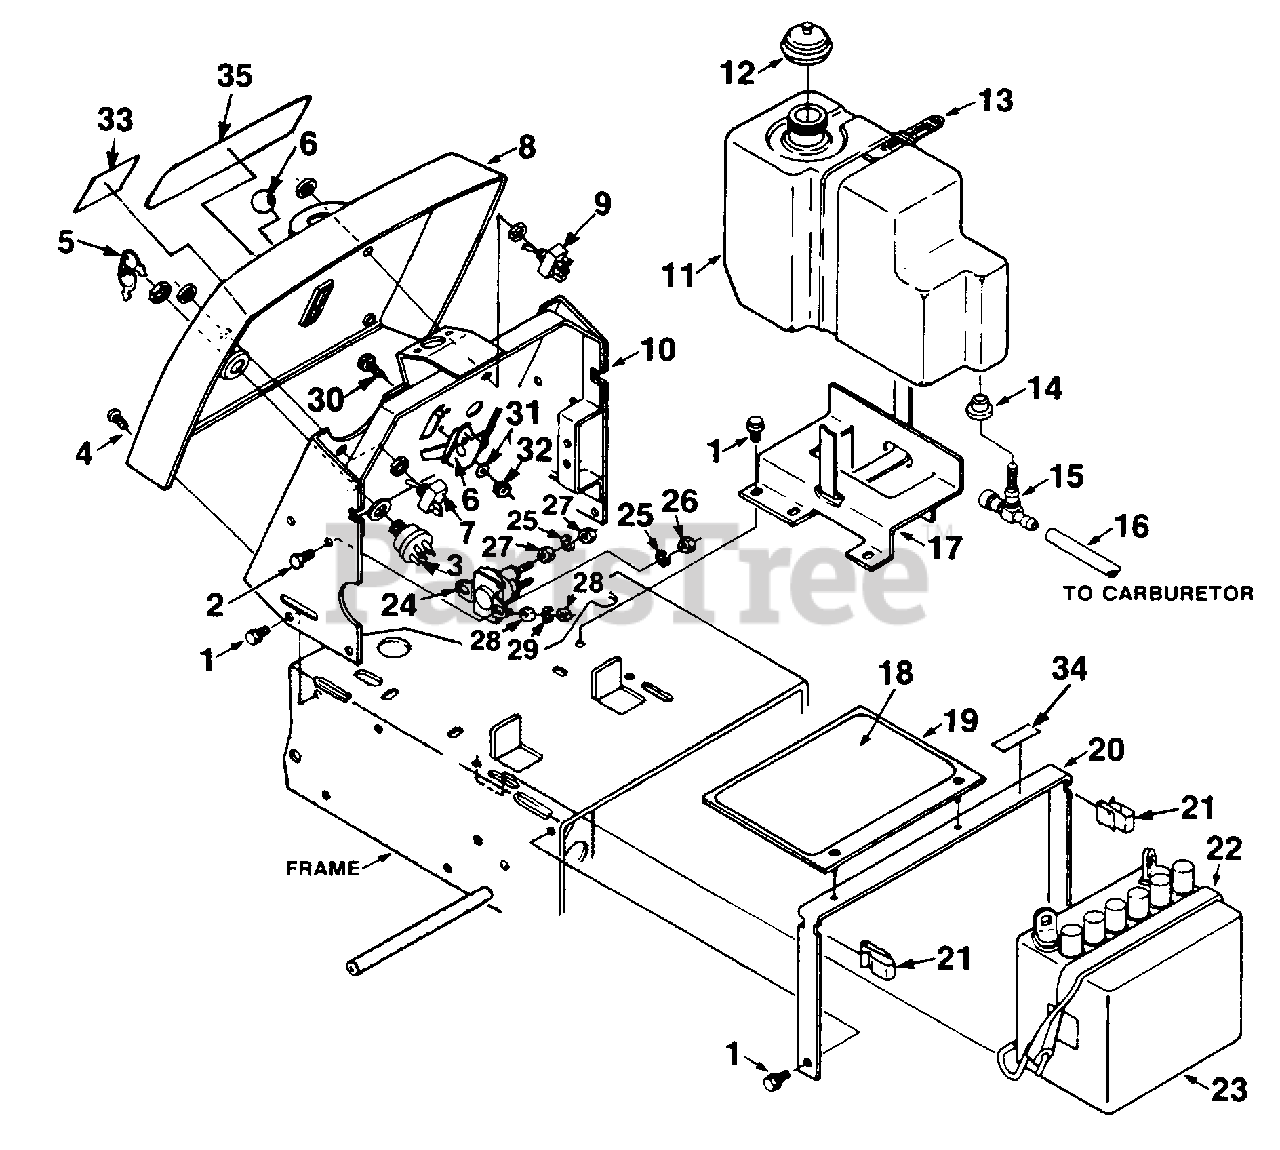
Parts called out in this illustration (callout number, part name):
1	BOLT- 1/4-14
2	SCREW- 1/4-20 x 1/2 hex
3	SWITCH- Key
4	SCREW- #10 x 3/4
7	SWITCH- Headlight
8	PANEL- Dash
9	SWITCH- PTO
10	CONTROL TOWER ASSY.
11	TANK- Gas
12	CAP- Fuel
13	STRAP- Gas tank
15	VALVE- Shut off
16	TUBING- Rubber
18	DECAL- Battery
19	COVER- Battery
22	STRAP- Hold down
25	WASHER- Lock 1/4
26	NUT- Hex 1/4-20
27	NUT- 1/4-20
28	NUT- Hex 8-32
29	WASHER- Lock #8
30	SCREW- 10-24 x 1/2
31	WASHER- Plain 1/4"
32	NUT- Hex Centerlock 10-24
33	DECAL- Throttle
34	DECAL- Gasohol
35	DECAL- Instruction
